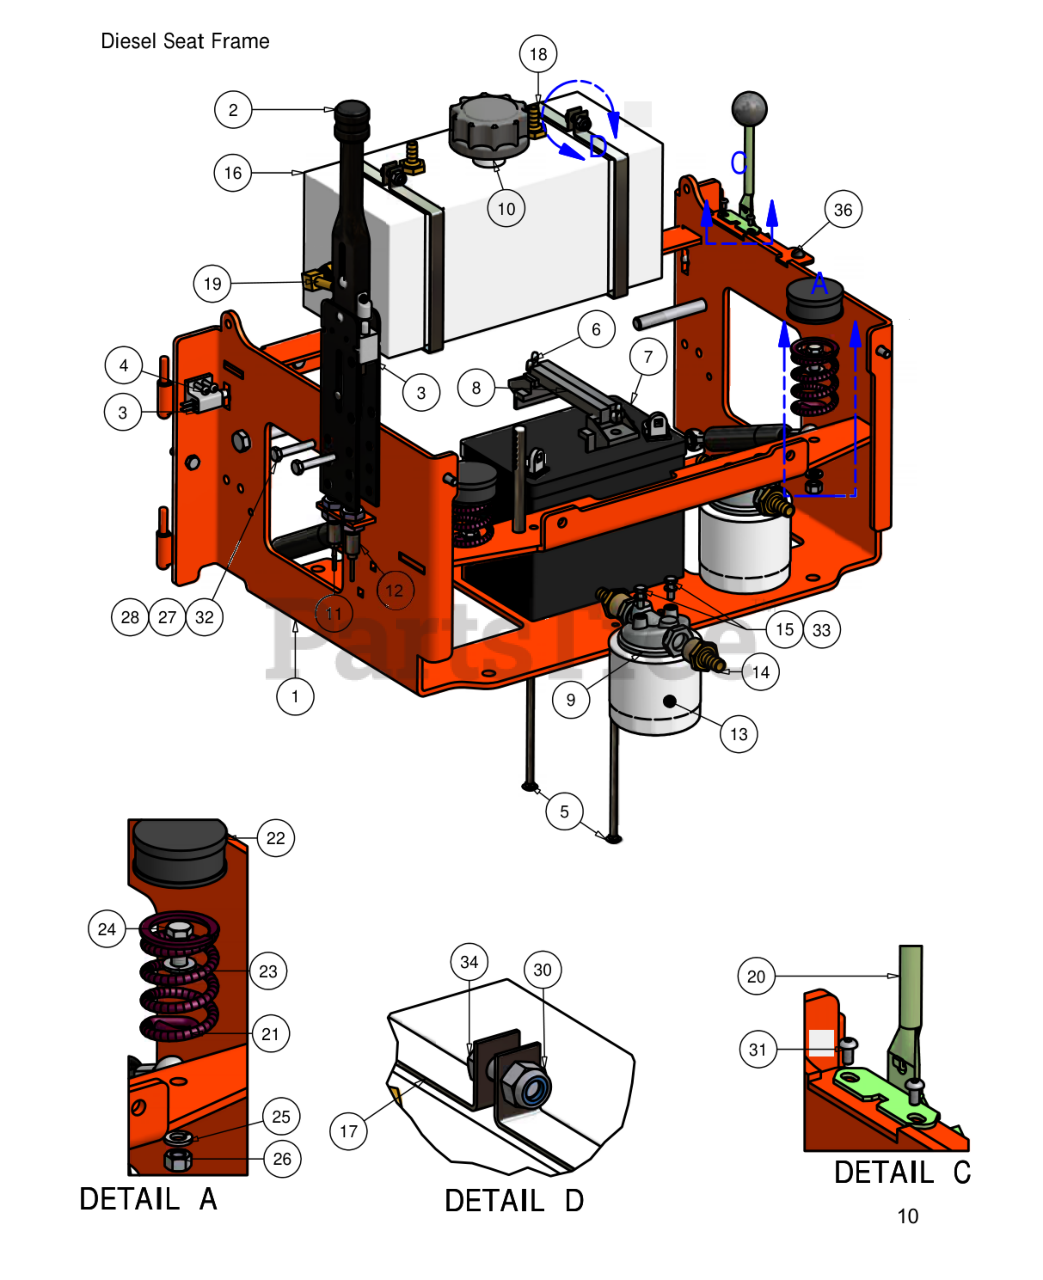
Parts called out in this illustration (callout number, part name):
1	Seat Frame
2	Brake Lever
3	Brake Handle Switch
4	1024 x 1" Bolt
5	9" Stove Bolt for Diesel (Aos gets 8")
6	1/4" Wing Nut
7	Diesel Battery
8	Battery hold-down
9	Filter Head
10	Hydraulic Tank Cap
11	Short Brake Cable
12	Long Brake Cable
13	Hydraulic Filter
14	1/2" x 1/2" Filter Head Fitting
15	1/4" x 3/4" Hex Bolt
16	Hydraulic Tank
17	Hydraulic Tank Strap
18	3/8" X 3/8" Hose Barb
19	1/2" x 1/2" Filter Head Fitting (90 Degree)
21	Seat Spring
22	1 1/2" Spring Cap Cover
23	3/8" Flat Washer
24	3/8" x 1 1/2" Hex Bolt
25	3/8" Lock Washer
26	3/8" Hex Nut
27	5/16" Lock Washer
30	5/16" Nylock Nut
31	1024 X 5/8" Buttonhead Bolt
32	5/16" x 1 3/4" Hex Bolt
33	1/4" Lock Washer
34	5/16" x 3/4" Hex Bolt
35	Piezo Buzzer
36	Momentary Start Switch- Diesel
